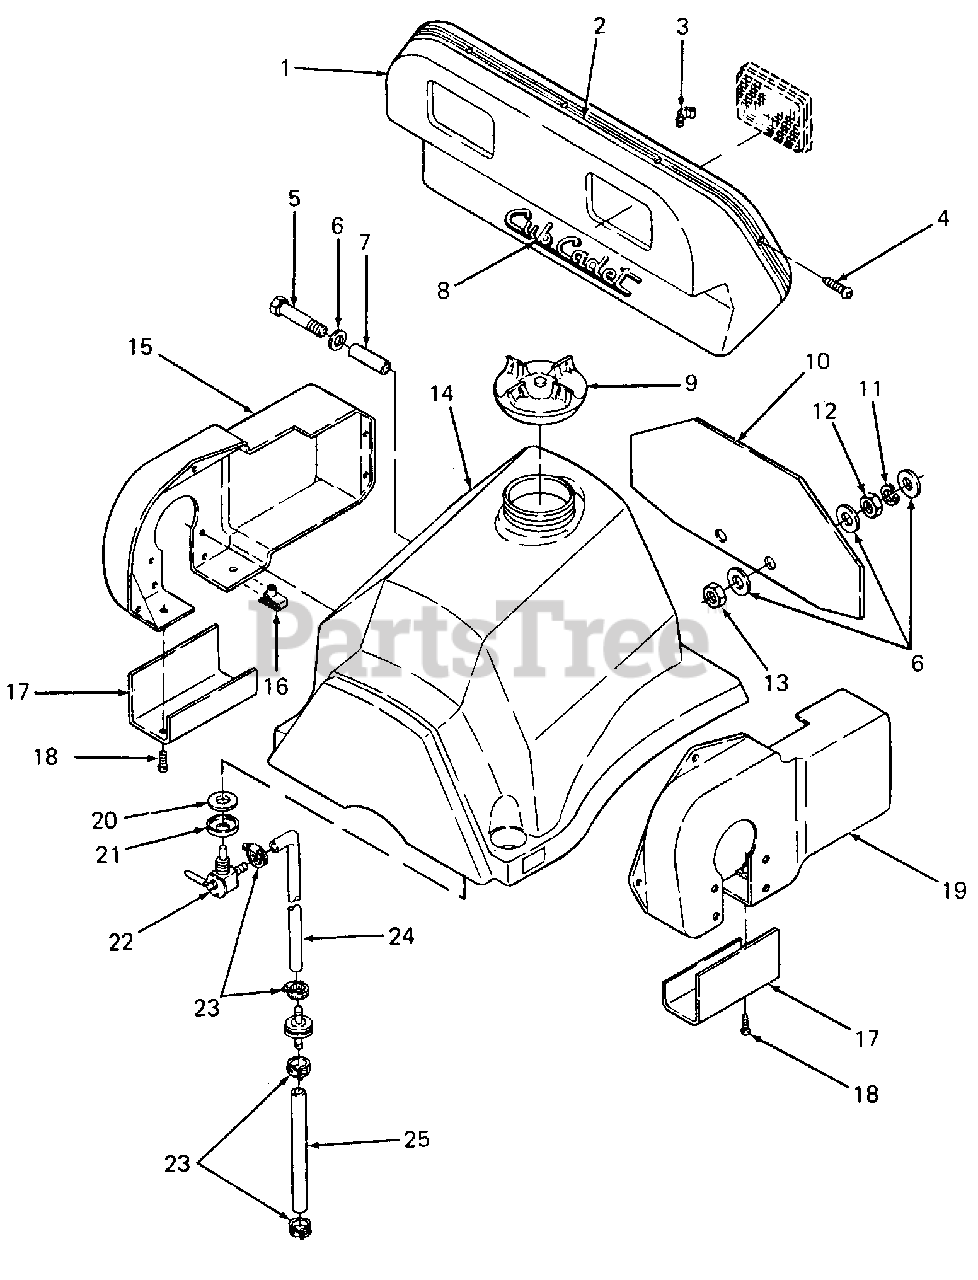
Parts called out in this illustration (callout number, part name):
1	Headlamp Housing
2	Kit, Power Unit Decal
3	Clip, Headlamp
4	Screw, Phillips Hd Tap, 1/4-14 X 5/8
5	Screw, Hex Cap, 3/8-16 x 3
6	Washer, Flat, .385 ID X .87 OD X .06
7	Spacer, Fuel Tank
8	Script, CCC
9	Cap, Fuel
10	Shield, Heat
11	Washer, Lock, 3/8
12	Nut, Hex, 3/8-16
13	Nut, Hex Center Lock, 3/8-16
15	Cover, Chain, RH
16	Nut, Panel, U-Type, 1/4-20
17	Bracket, Chain Guard
18	Screw, Phillips Truss Mach, 1/4-20 X .75
19	Cover, Chain, LH
20	Seal, Gas Tank
21	Cap, Shut Off Seal
22	Shut Off, Fuel
23	Clamp, Hose
24	Line, Fuel Tank to Filter
25	Line, Filter to Engine
